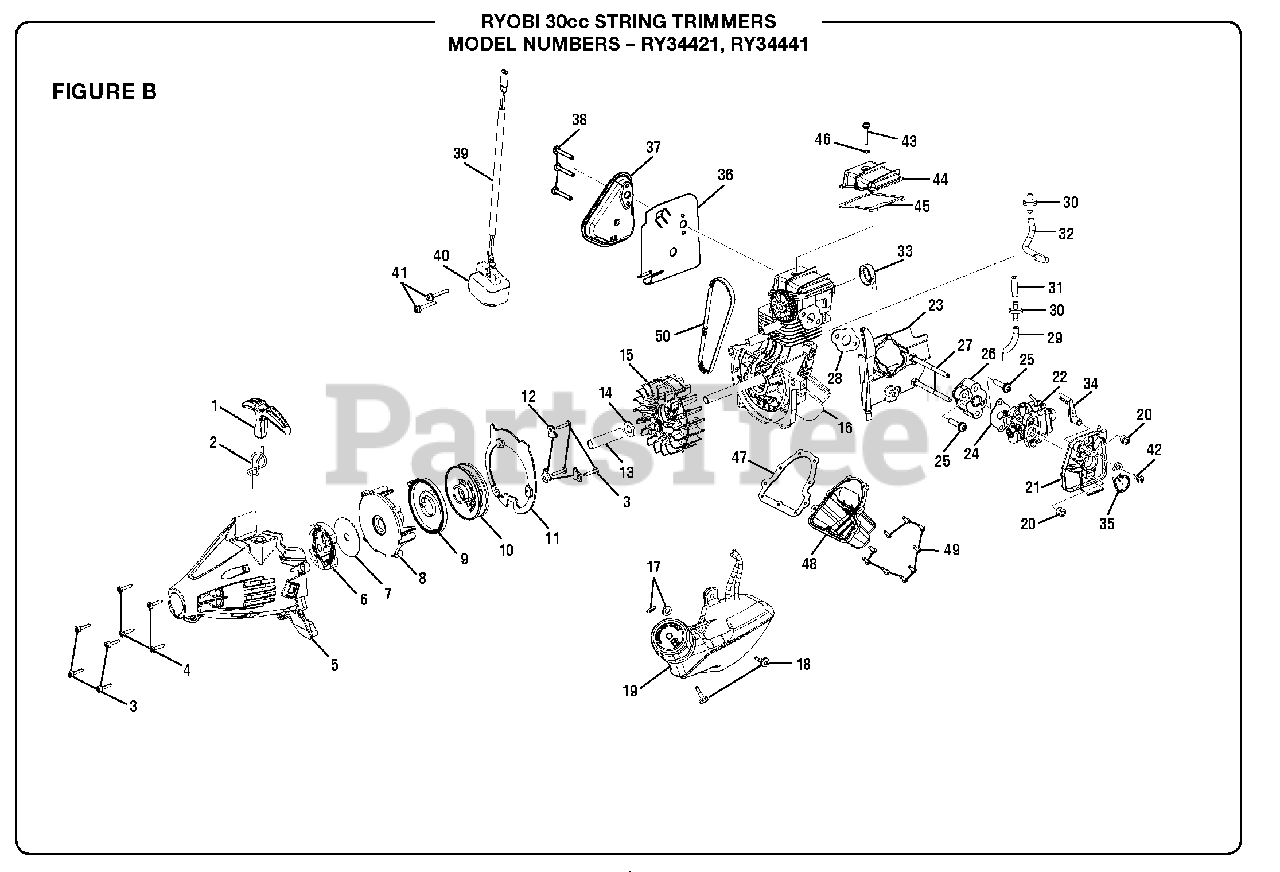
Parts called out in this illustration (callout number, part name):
1	Starter Grip
2	Starter Rope (42 in)
3	Screw (M4 x 18 mm)
4	Screw (M4 x 16 mm)
5	Starter Housing Assembly
6	Clutch Assembly
8	Starter Baffle
9	Spring & Container
10	Starter Pulley
12	Pulley Retainer
13	Spacer Tube
14	Washer
15	Flywheel Assembly
16	Short Block Assembly
18	Screw (M4)
19	Fuel Tank & Cap Assembly
20	Hex Nut (M5 x 0.8)
21	Air Filter Base
22	Carburetor Assembly
23	Air Baffle
24	Carburetor Gasket
25	Screw (M5 x 23 mm)
27	Bolt (M5 x 63 mm)
28	Heat Dam Gasket
29	Breather Hose
30	Check Valve
31	Breather Hose
32	Breather Hose
33	Breather Fitting
34	Choke Lever
35	Choke Plate
36	Muffler Gasket
37	Muffler Assembly
38	Muffler Bolt (M5 x 42 mm)
39	Electrical Lead Wire Assembly
40	Ignition Module
41	Screw (M4 x 19 mm)
42	Screw (M4 x 12 mm)
43	Screw (M4 x 27 mm Total, w/14 mm Threaded)
44	Cam Cover
49	Screw (M4 x 12 mm)
50	Timing Belt
